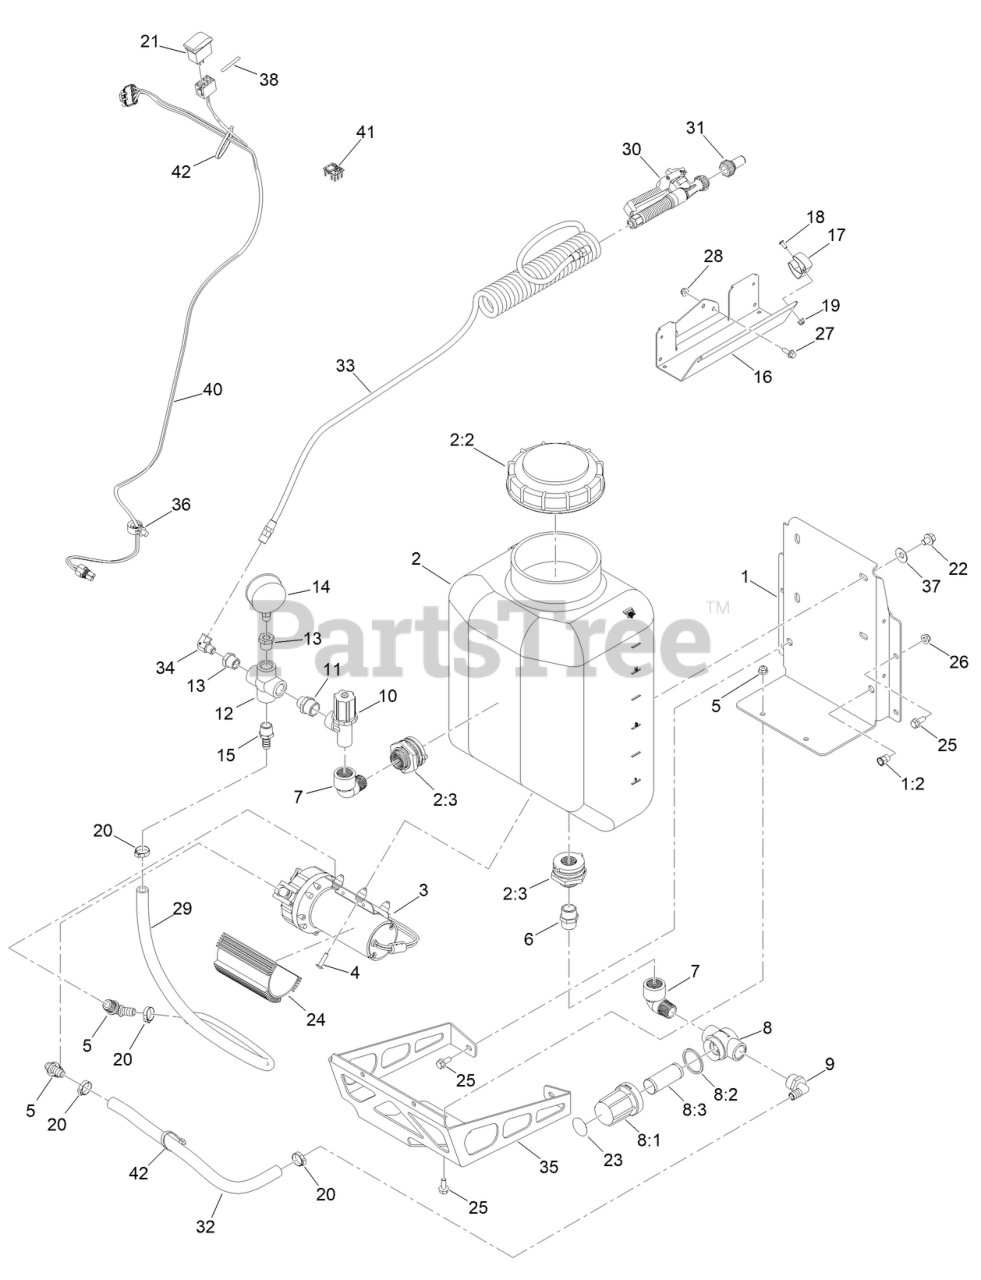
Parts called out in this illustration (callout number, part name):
1	BRACKET ASM, 7 GAL ISO TANK
1:2	NUT-CLINCH
2	7 GAL AUX/ISO TANK ASM
2:2	CAP-TANK, SPRAY
2:3	FITTING-BULKHEAD
3	PUMP-5.3 GPM
4	SCREW-HSBHF
5	FITTING-ELBOW, BARBED
6	FITTING-NIPPLE
7	ELBOW-90 DEG
8	STRAINER-INLINE
8:1	BOWL-STRAINER
8:2	GASKET-HEAD, LINE STRAINER
8:3	SCREEN-STRAINER, 50 MESH
9	FITTING-ELBOW, 90
10	VALVE-THROTTLE
11	FITTING-NIPPLE
13	FITTING-REDUCER
14	GAUGE-PLAIN
15	FITTING-HOSEBARB
16	TRAY-HOSE
17	HOLDER-TOOL, CLIP
18	SCREW-HSBH
19	NUT-HEX FLANGE
20	CLAMP-OETIKER, 167
21	SWITCH-ROCKER
22	SCREW-HHF
23	DECAL-CAP, STRAINER
24	HEATSINK-3.0"
25	SCREW-HHF
26	NUT-HEX FLANGE
27	SCREW-HHF
28	NUT-HEX FLANGE
29	HOSE-COILED, 15 FT
30	GUN-SPRAY, SPOT
31	TIP-SPRAY, #12 SPOT
32	HOSE-SPRAY
33	HOSE-SPRAY
34	FITTING-ELBOW, 90
35	BRACKET-7 GAL ISO TANK
36	CLIP-TIE
37	WASHER-SPRING
38	DECAL-SPRAY PUMP ON/OFF
40	HARNESS-ISO PUMP
41	PCA-HIGH POWER SSR
42	TIE-CABLE
99	INSTRUCTION SHEET
